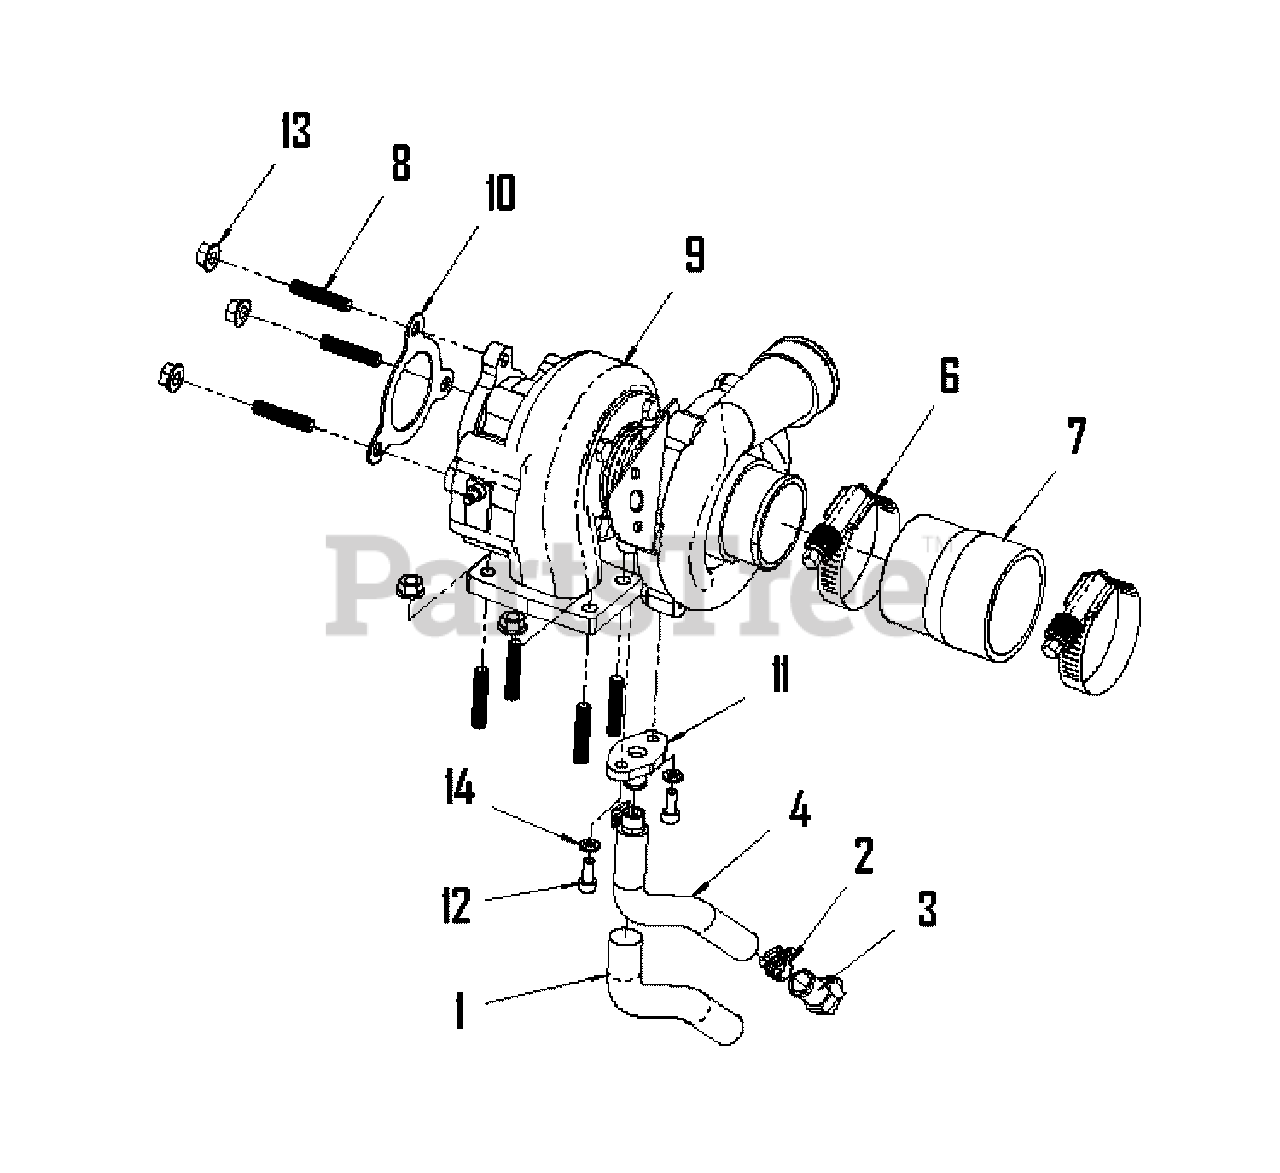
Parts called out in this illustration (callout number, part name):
1	SLEEVE
3	*FITTING
8	*STUD
10	GASKET
11	*FITTING
12	*BOLT
13	*NUT
14	*WASHER
